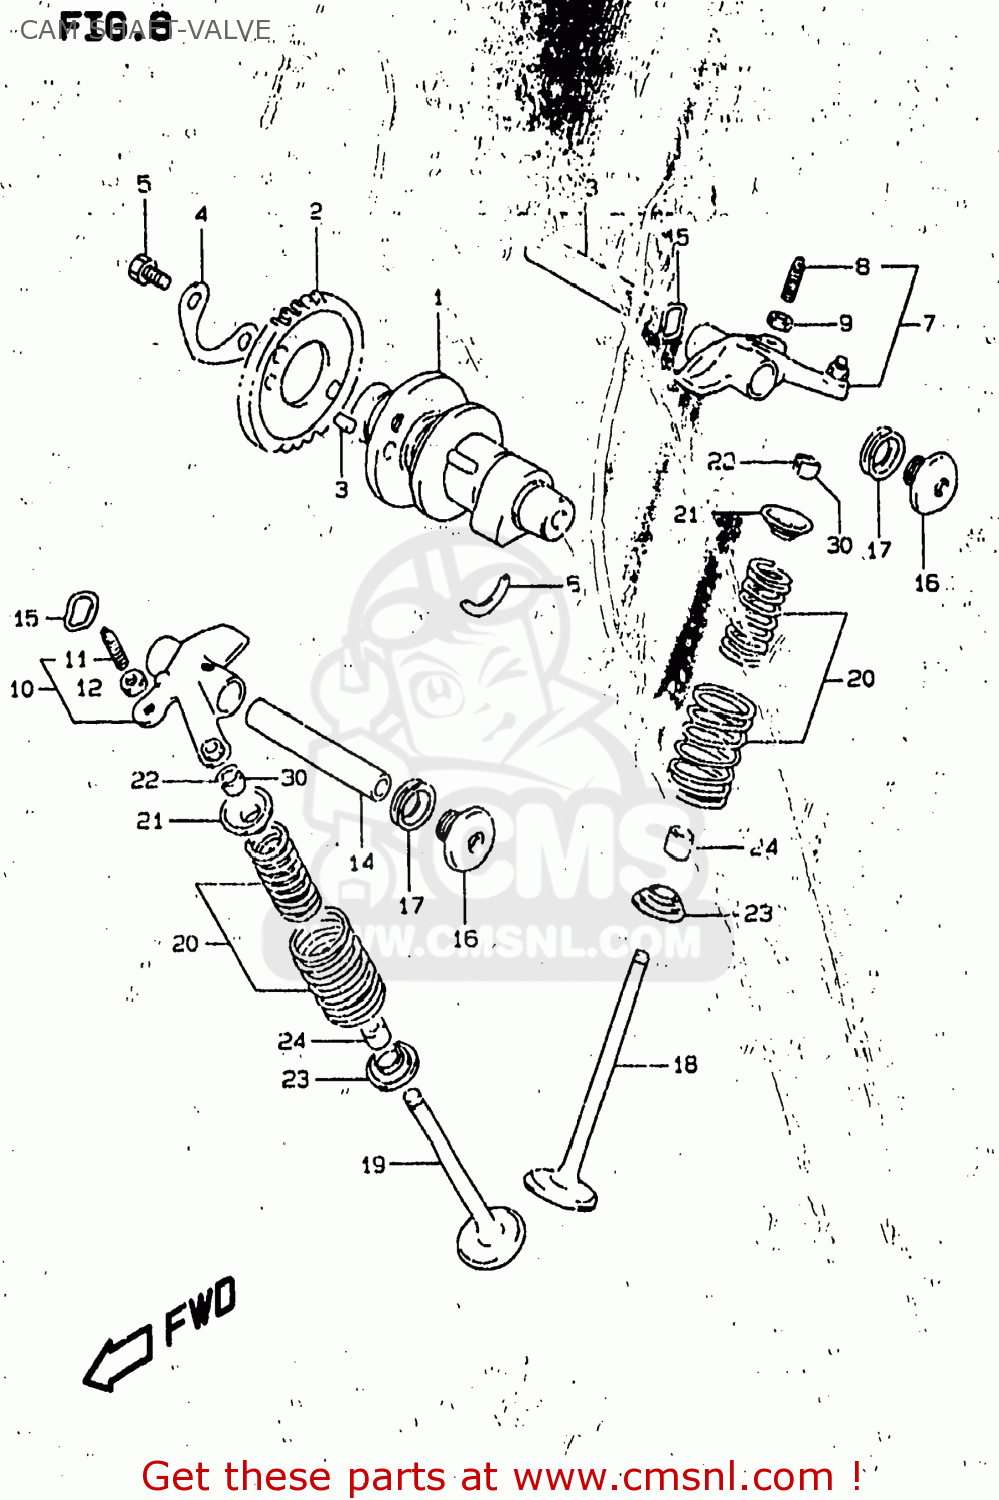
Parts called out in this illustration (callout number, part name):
1	CAMSHAFT COMP
2	SPROCKET,CAMSHAFT
3	PIN(5X8)
4	WASHER,SPROCKET
5	BOLT(6X10.5)
6	C RING
7	ARM,VALVE ROCKER,INTAKE
8	SCREW,TAPPET ADJUSTING
9	NUT,TAPPET ADJUSTING
10	ARM,VALVE ROCKER EXHAUST
11	SCREW,TAPPET ADJUSTING
12	NUT,TAPPET ADJUSTING
13	SHAFT,VALVE ROCKER ARM INTAKE
14	SHAFT,VALVE ROCKER ARM EXHAUST
15	WASHER
16	PLUG,14X12
17	GASKET(13.8X18.8X4.8) (NAS)
18	VALVE,INTAKE
19	VALVE,EXHAUST
20	SPRING SET,VALVE
21	RETAINER,VALVE SPRING
22	COTTER VALVE
23	SEAT,VALVE SPRING
24	SEAL,OIL(5X10X9.7)
